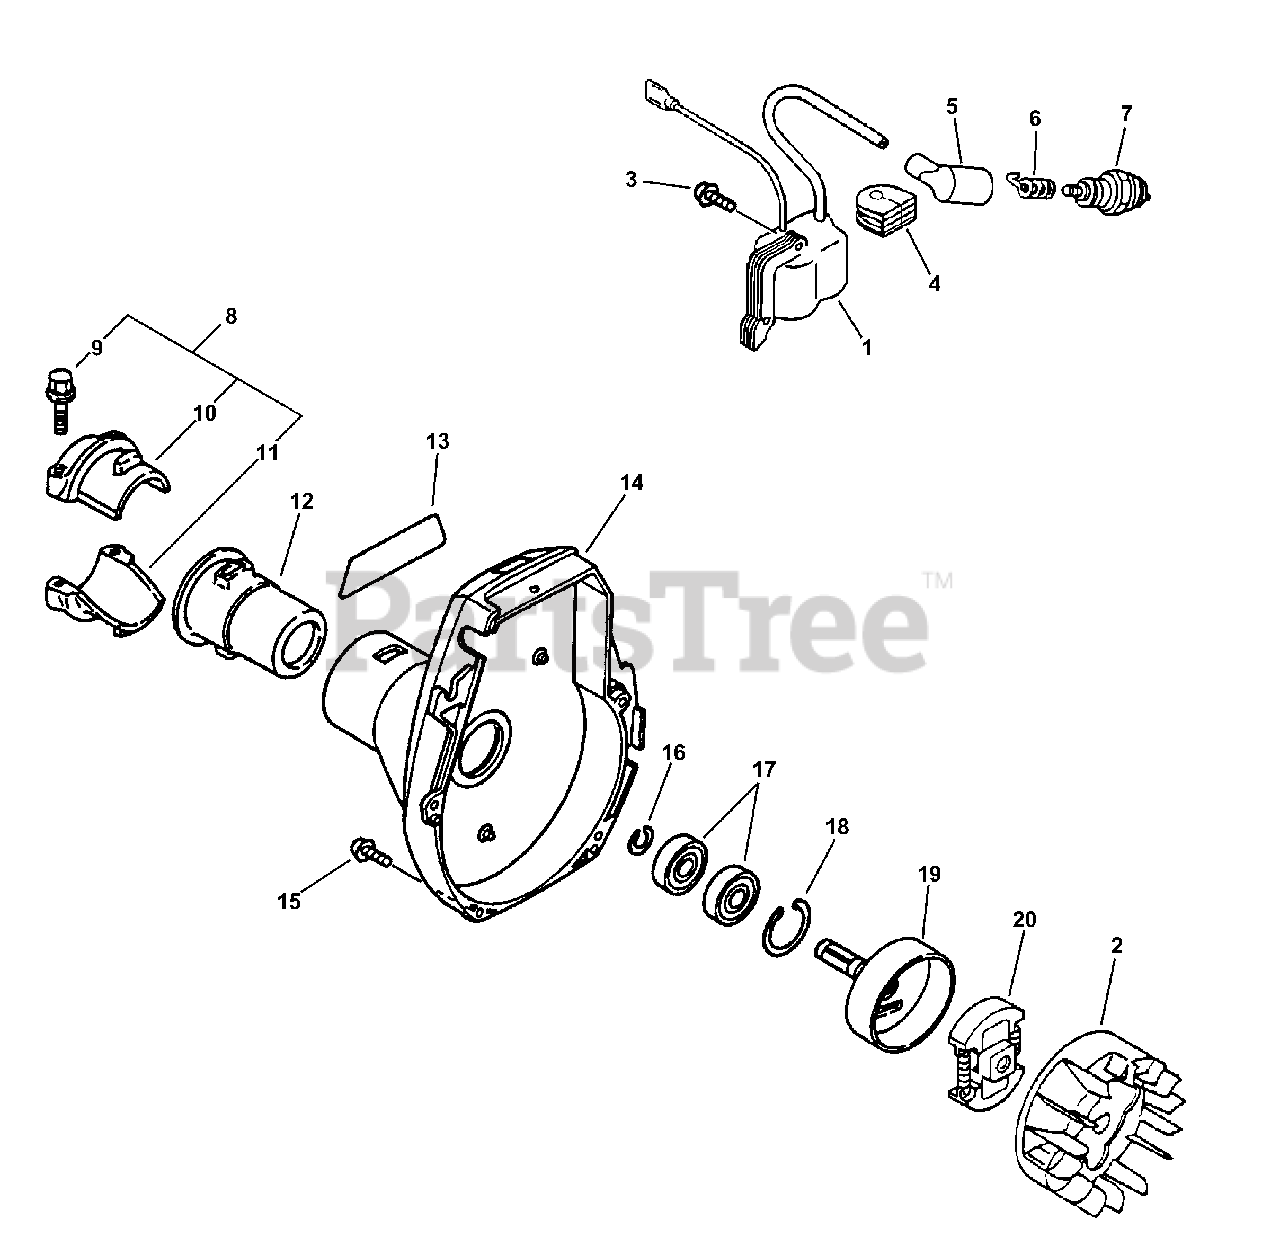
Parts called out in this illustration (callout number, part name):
1	COIL, IGNITION
2	FLYWHEEL
3	SCREW - 4X22
5	CAP, SPARK PLUG
6	TERMINAL, SPARK PLUG CAP
7	SPARK PLUG -- BPM-7A
8	MAIN PIPE CLAMP KIT
9	BOLT - 5X25
10	CLAMP, MAIN PIPE - UPPER
11	CLAMP, MAIN PIPE - LOWER
13	LABEL - MODEL SRM-2100
13	LABEL - MODEL SRM-2110
14	CASE, FAN
15	SCREW - 4X16
16	RING, RETAINING - 12
17	BEARING, BALL - 6001
18	RING, RETAINING - 28
19	DRUM, CLUTCH
20	CLUTCH ASSY
